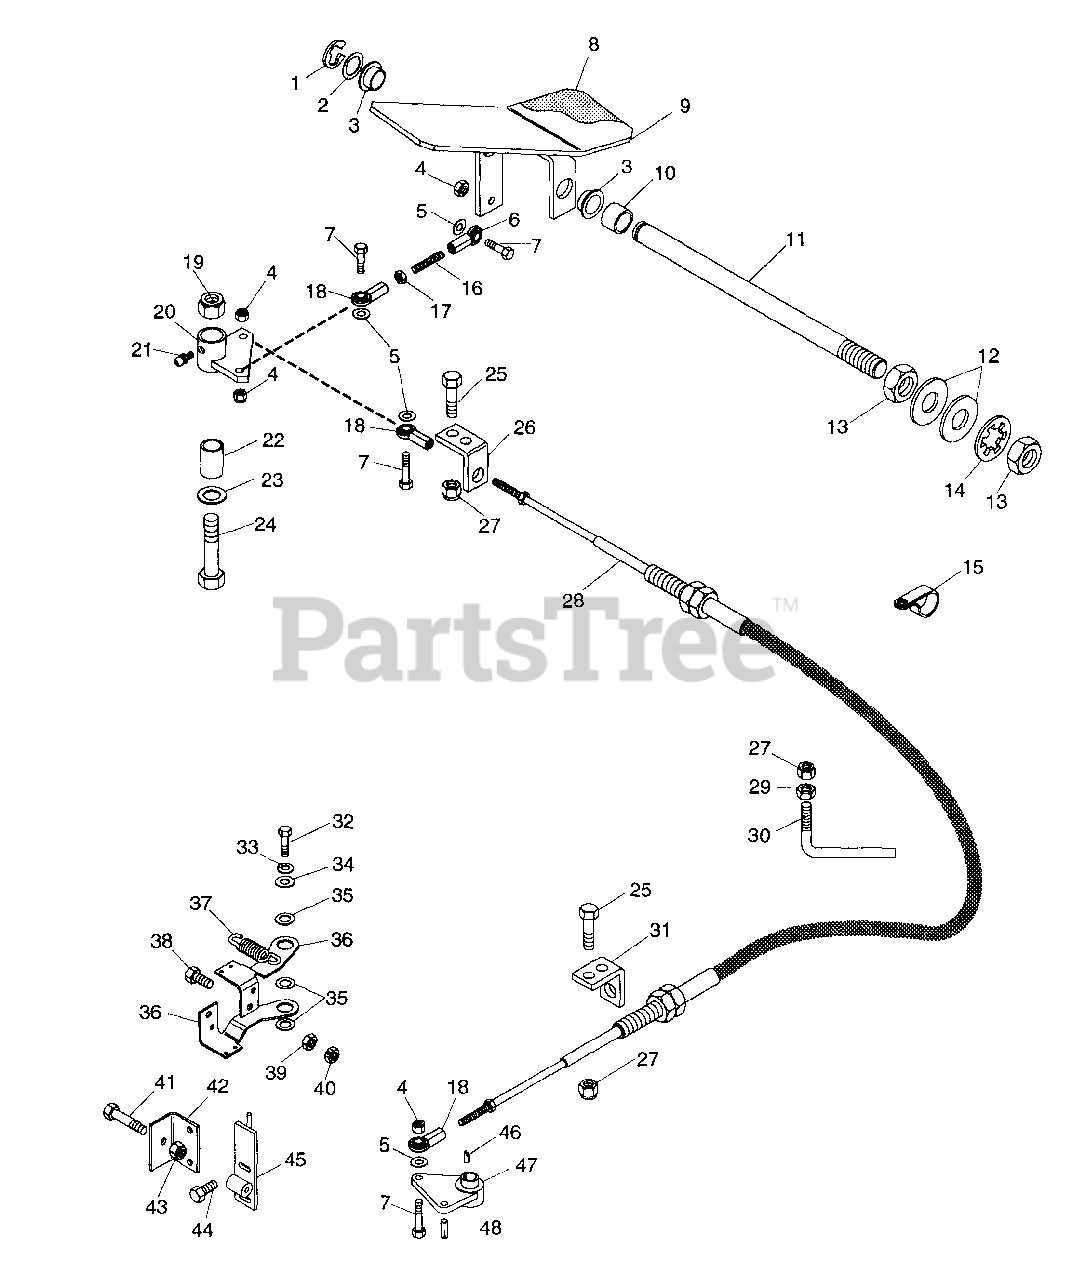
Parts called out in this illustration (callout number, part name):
1	Ring-Retaining-External .574 x .050
2	Bearing-Needle-Thrust .752 x 1.24 x .031
3	Bushing-Flange .762 x 1.0 x .580 x 1.48
4	Nut-Locking-Nylon .250-20
5	Washer-Flat-Steel .281 x .620 x .065
6	Rod End Left Hand
7	Bolt-Hex .25-20 x 1.25 Grade 5
8	Cover, Pedal
9	Weldment, Pedal
10	Bushing, Sleeve .782 x 1.00 x .710
11	Shaft, Pedal
12	Washer-Flat .812 x 1.469 x .134
13	Nut-Jam .75-16
14	Washer-Lock Internal .750
15	Clamp, Cushioned Steel
16	Rod
17	Nut-Jam-Hex .250-28
18	Rod End, Female 1/4-28
19	Nut-Locking-Nylon .50-13
20	Weldment, Lever
21	Fitting-Lube .25-28 x .256
22	Spacer, .562 x .855 x 1.56
23	Washer-Flat-Steel .500 x 1.250 x .083
24	Bolt-Hex .50-13 x 2.50 Grade 5
25	Bolt-Hex .38-16 x 1.00 Grade 5
26	Bracket, Cable
27	Nut-Locking-Nylon .375-16
28	Cable, Forward-Reverse
29	Nut-Jam .375-16
30	Rod, Cable Guide
31	Bracket, Cable
32	Bolt-Hex .25-20 x 1.50 Grade 5
33	Washer-Lock .250
34	Washer-Flat-Steel .281 x 1.250 x .062
35	Washer-Flat-Steel .760 x 1.125 x .030
36	Lever, Neutral
37	Spring-Tension .075 x .75 x 2.25
38	Bolt-Hex .31-24 x .75 Grade 5
39	Nut-Jam .312-24
40	Nut-Locking-Center .312-24
41	Bolt-Hex .31-18 x 1.25
42	Bracket
43	Nut-Locking-Nylon .312-18
44	Screw-Tapping .313-18 x .875
45	Weldment, Neutral Stop
46	Key, Woodruff .13 x .50
47	Arm, Transmission Control
48	Pin-Groove .250 x .75
